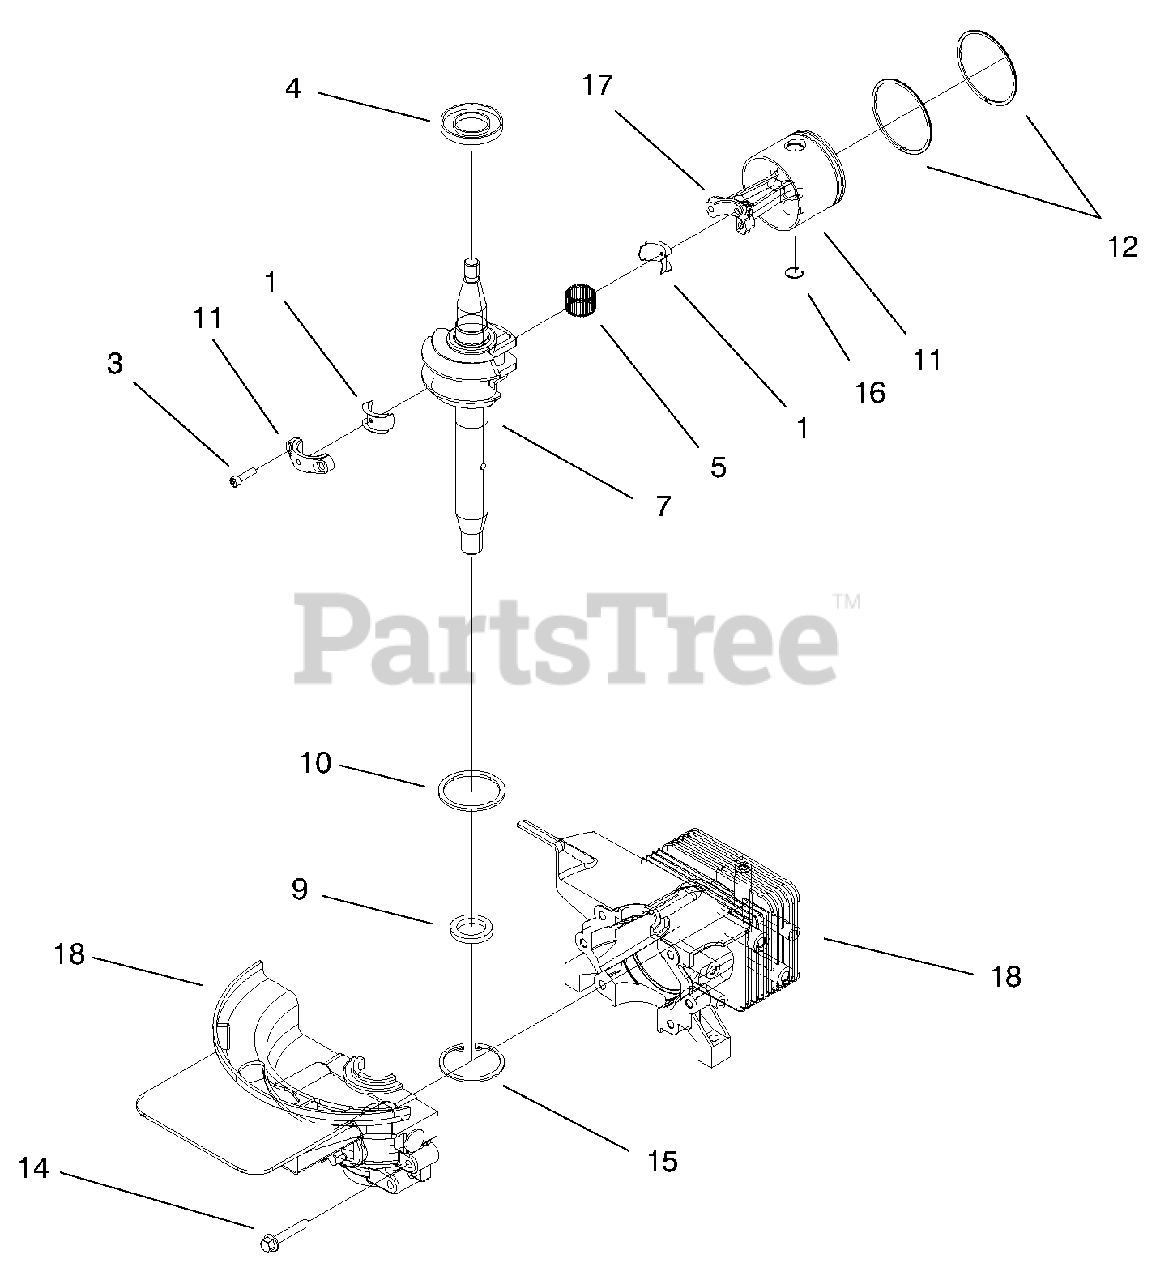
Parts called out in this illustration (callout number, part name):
1	Split Liner ASM
4	Oil Seal
5	Needle Bearing & Bearing ASM
7	Crankshaft
9	Oil Seal
10	Ring Retaining
11	Piston & Conn Rod ASM
12	Ring Set
14	Screw-HWH
15	Ring-Retaining
16	Ring-Retaining
17	Connecting Rod ASM
18	Cylinder & Crankcase
